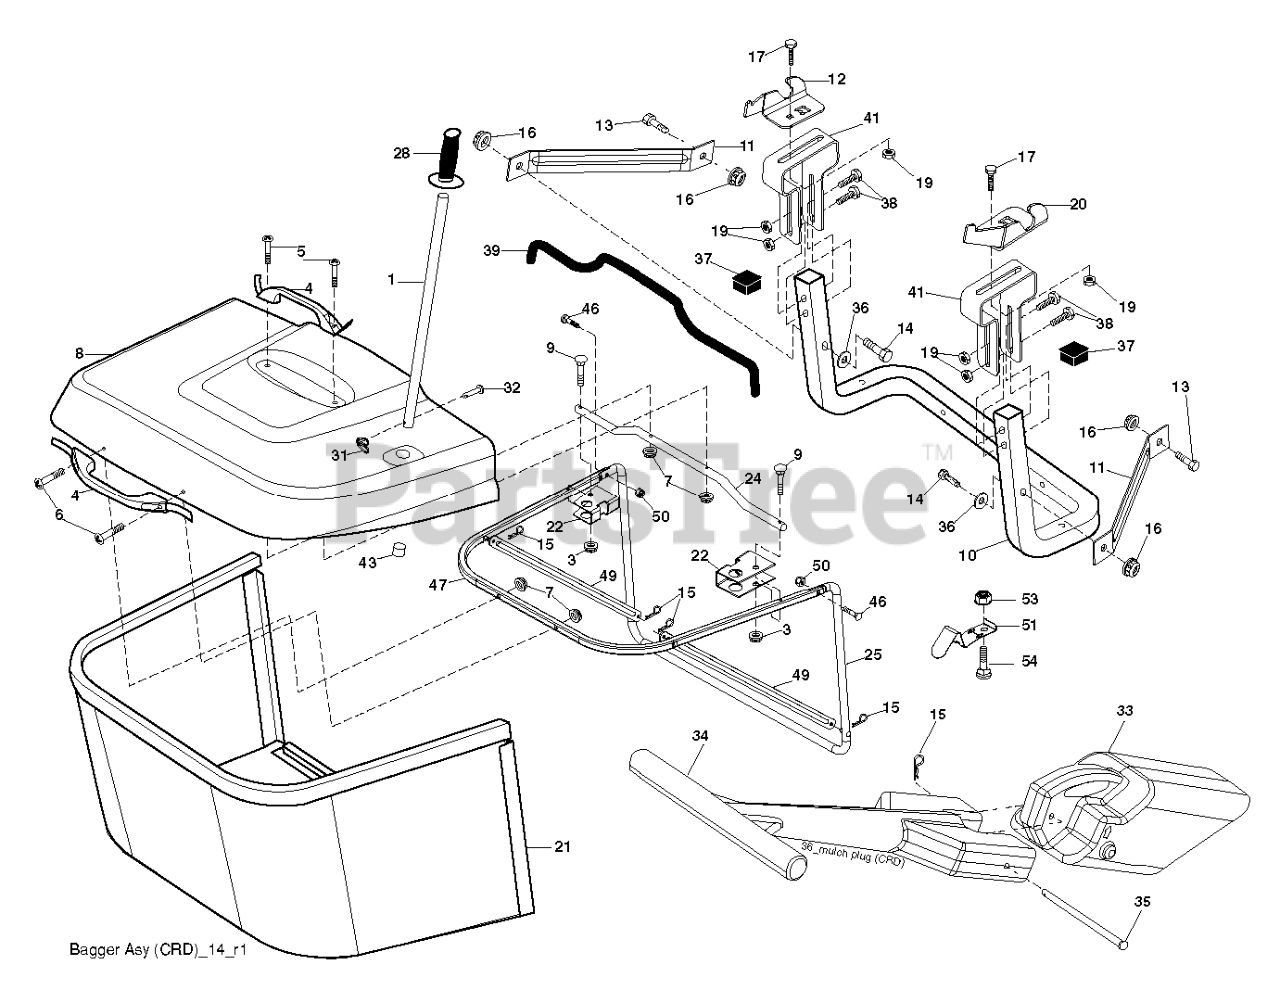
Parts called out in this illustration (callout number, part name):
1	TUBE HANDLE
3	NUT T
4	HANDLE.BAGGER.W/LVRS.BLK.CRD
5	SCREW.PAN.HEAD
6	REPL BY 532 75 00-29
8	COVER.PNT.BGR.CRD.WSLOTS.MS668
9	Bolt Carriage 1/4-20 x 2.25d x Gr.5
10	TUBE
11	BRACKET.SUPPORT.UPPER.BAG.CRD
12	BRKT PIVOT
14	BOLT-HEX EAK
15	RETAINER-SPRNG RB
16	NUT LOCK FLG 3/8-16 UNC
17	RP BOLT 5/16-18 X3/4 ZN/YEL GR
19	NUT LOCK HEX FLANGE 5/16-18
20	BRKT.PIVOT.RH.CRD
21	BAGGER.ASM.CRD.2007
22	BRKT.SIDE.BAG.CRD
24	TUBE.PIVOT.BAG.CRD.BLACK
25	PIPE
28	GRIP.HANDLE.BLACK
31	RETAINER CLIP
32	RIVET,DRILLED
33	PLUG.MULCHER.92 CRD
34	HANDLE.MULCHER.92.CRD (2 2)
36	WASHER
37	Plug Support Bagger CRD
38	BOLT.5/16-18X2.5
39	SEAL.BAGGER.CRD
41	BRKT.VERT.ADJ.BAGGER.CRD
43	PLUG, TUBING END
46	BOLT.CARRIAGE.5/16-18
47	PIPE
49	ROD
50	NUT.71038.31-18.HEX.NYLOCK
51	LATCH
53	NUT
54	BOLT
